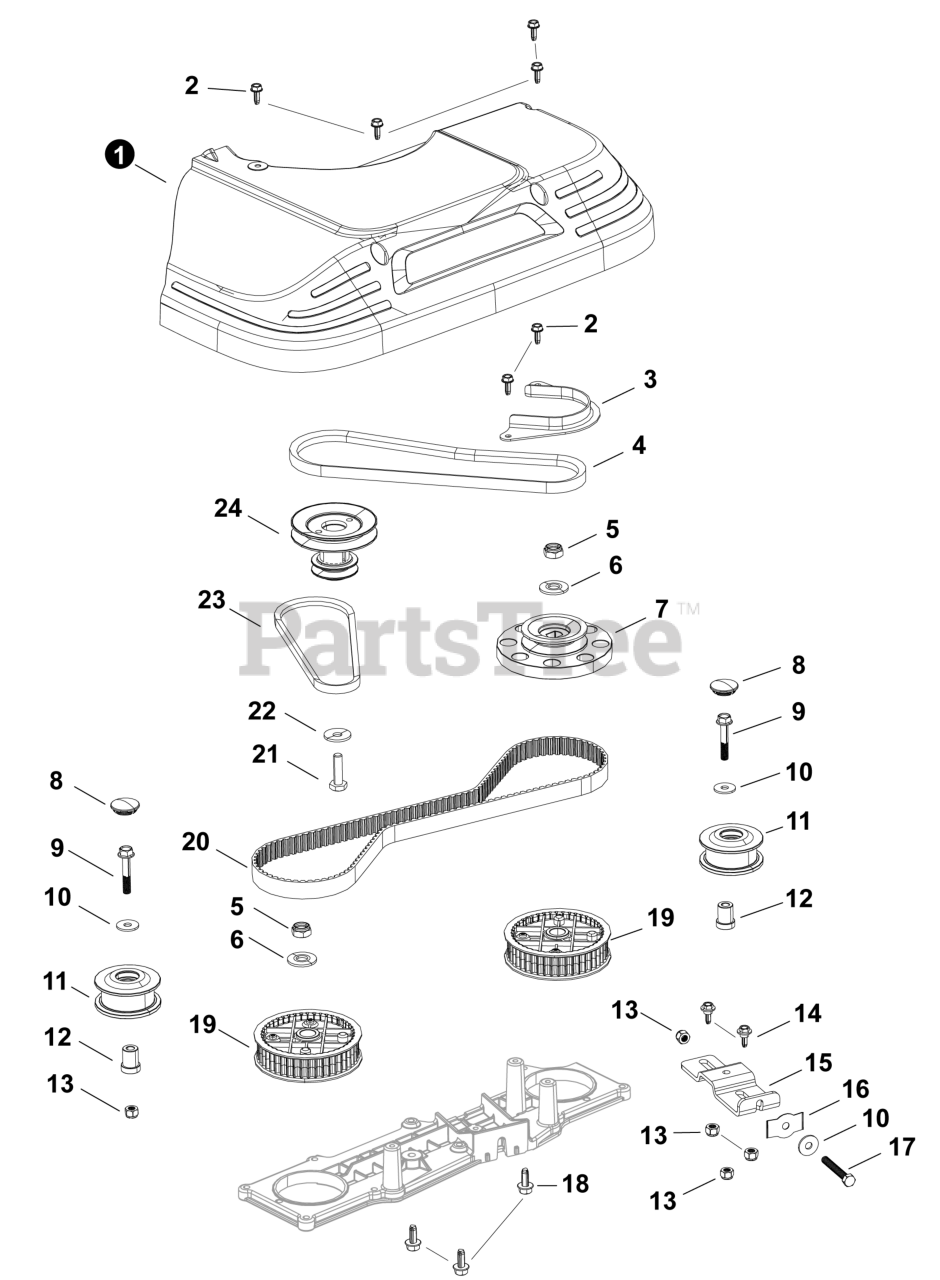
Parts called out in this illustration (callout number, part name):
1	COVER, TIMING BELT
3	GUIDE, BELT
4	BELT, BLADE DRIVE
7	PULLEY, BLADE BRAKE
8	COVER, DUST
11	TENSIONER, TIMING BELT
12	SLEEVE, TENSIONER
15	BRACKET, TENSIONER
19	PULLEY, TIMING
20	BELT, TIMING
21	BOLT, BLADE
23	BELT, SELF-PROPEL
